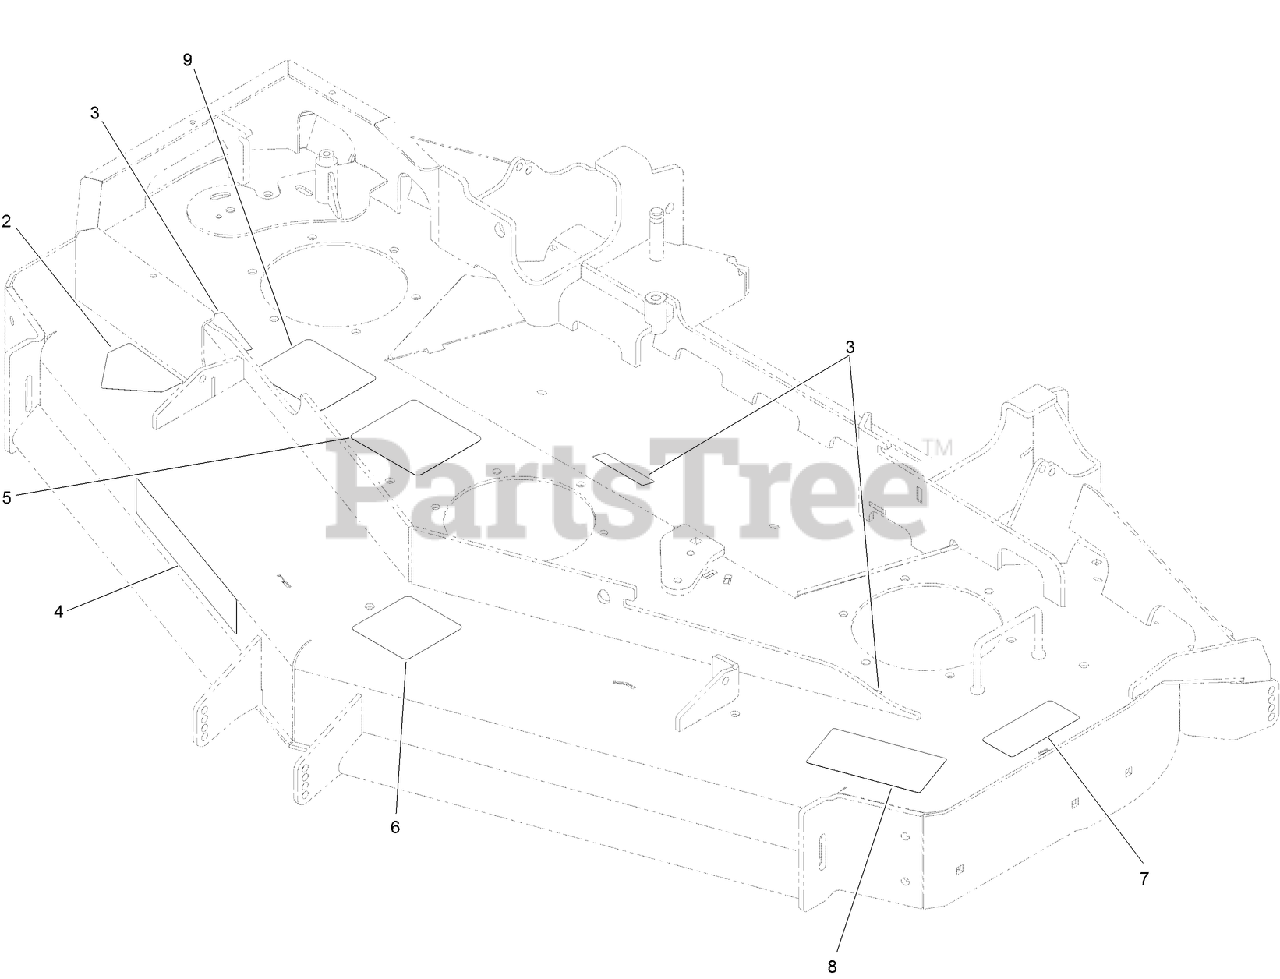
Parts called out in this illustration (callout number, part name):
2	DECAL-DANGER
3	DECAL-COVER, MISSING
5	DECAL-ROUTING, DECK BELT
6	Decal, Anti-Scalp
7	DECAL-TORQUE
8	DECAL-DANGER, THROWN OBJECT
9	DECAL-SPINDLE, COUNTER ROTATING
